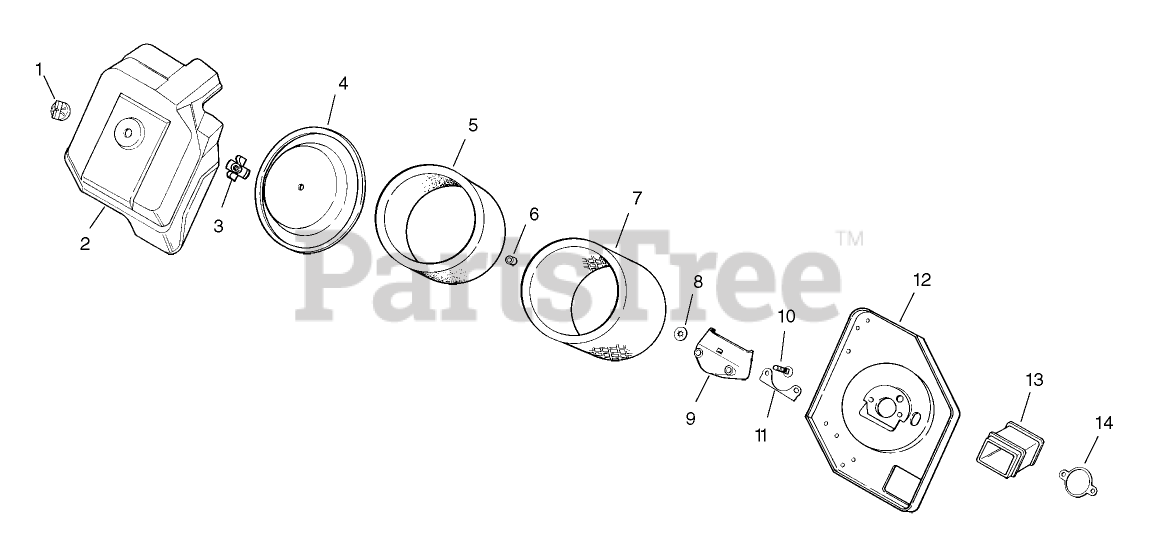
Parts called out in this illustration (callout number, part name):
1	Knob-Cover
2	Cover-Air Cleaner Base
3	Nut-Wing
4	Cover-Air Cleaner Element
5	Precleaner-Element
6	SEAL-AIR CLEANER, INNER
7	Element-Air Cleaner
8	Retainer-Ring
9	Cup-Fuel, Spit-Back
10	Bolt-Round Head, Square Neck
11	Gasket-Collector, Plate
12	Base-Air Cleaner
13	Tube-Air Intake
14	Gasket-Base, Air Cleaner
